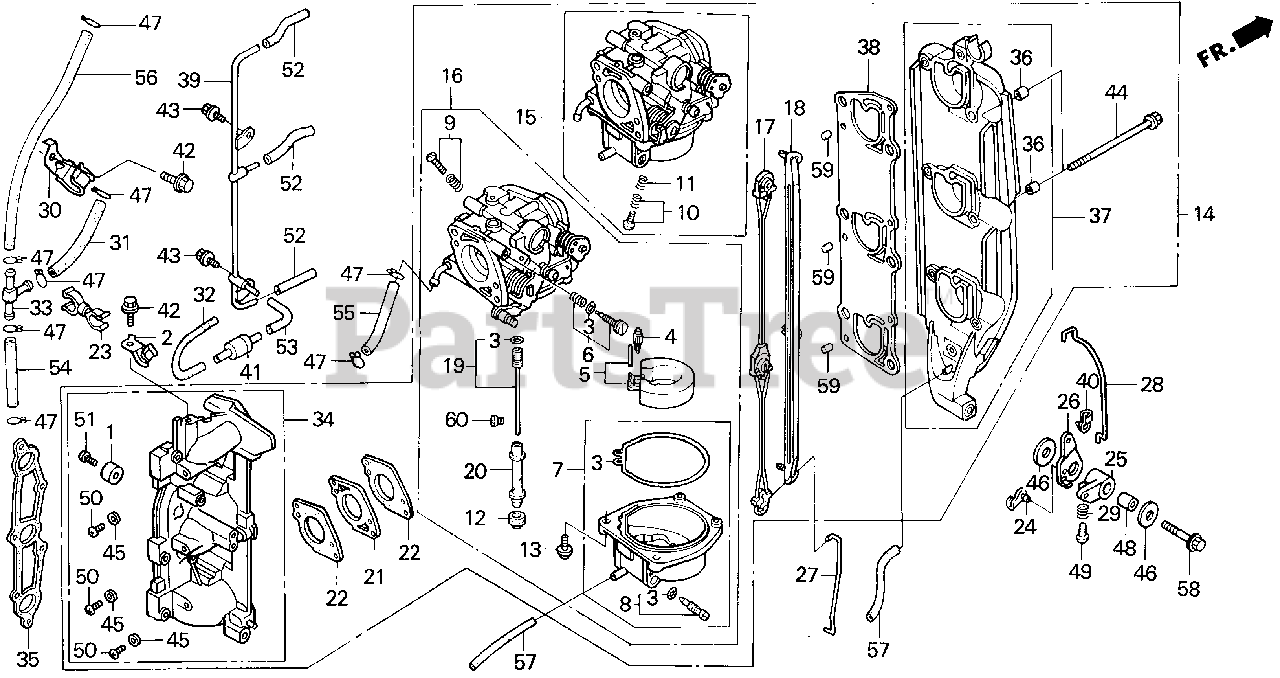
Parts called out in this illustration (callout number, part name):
1	METAL, ANODE
2	CLAMP, TUBE
3	GASKET SET
4	VALVE SET, FLOAT
7	CHAMBER SET, FLOAT
8	SCREW SET, DRAIN
12	SCREW, PLUG
13	SCREW-WASHER
14	CARBURETOR ASSY. (BG10B C) *NH8* (DARK GRAY)
14	CARBURETOR ASSY. (BG10B B) *NH8* (DARK GRAY)
15	CARBURETOR ASSY. (#1/#2)
16	CARBURETOR ASSY. (#3)
17	LEVER, LINK
18	LINE, CHOKE
19	JET SET (#35)
20	NOZZLE, MAIN
21	INSULATOR, CARBURETOR
22	GASKET, CARBURETOR
23	CLAMP, FUEL TUBE (A)
24	JOINT, ROD
25	ARM A, CHOKE
26	ARM B, CHOKE
27	ROD, CHOKE
28	ROD, CHOKE KNOB
29	SPRING, CHOKE ARM ADJUSTING
30	CLAMP, FUEL TUBE
31	TUBE C, FUEL
32	TUBE D, FUEL
33	PIPE, THREE-WAY JOINT
34	MANIFOLD ASSY., IN. *NH8* (DARK GRAY)
35	GASKET, IN. MANIFOLD
36	COLLAR, DISTANCE (6.5X11X7.5)
37	PLATE, MUFFLER
38	GASKET, MUFFLER PLATE
39	PIPE, INSTALL
40	BUSH, LINKAGE
41	VALVE, DASHPOT CHECK
42	BOLT, FLANGE (6X12)
43	BOLT, FLANGE (5X10)
44	BOLT, FLANGE (6X97)
45	WASHER, SEALING (5MM)
46	WASHER, PLAIN (6MM)
47	CLIP, TUBE (B10)
48	COLLAR, DISTANCE (6.5X10.5X16)
49	SCREW, PAN (4X16)
50	SCREW, PAN (5X10)
51	SCREW, PAN (6X18)
52	BULK HOSE, FUEL (3.5X3000) (3.5X45)
53	BULK HOSE, FUEL (3.5X3000) (3.5X65)
54	BULK HOSE, FUEL (5.5X8000) (5.5X55)
55	BULK HOSE, FUEL (5.5X8000) (5.5X70)
56	BULK HOSE, FUEL (5.5X8000) (5.5X175)
57	BULK HOSE, VINYL (3.5X6.5X8000) (3.5X6.5X130)
58	BOLT, FLANGE (6X28)
59	ROLLER (6X15)
60	JET, MAIN (#95)
60	JET, MAIN (#98)
60	JET, MAIN (#100)
